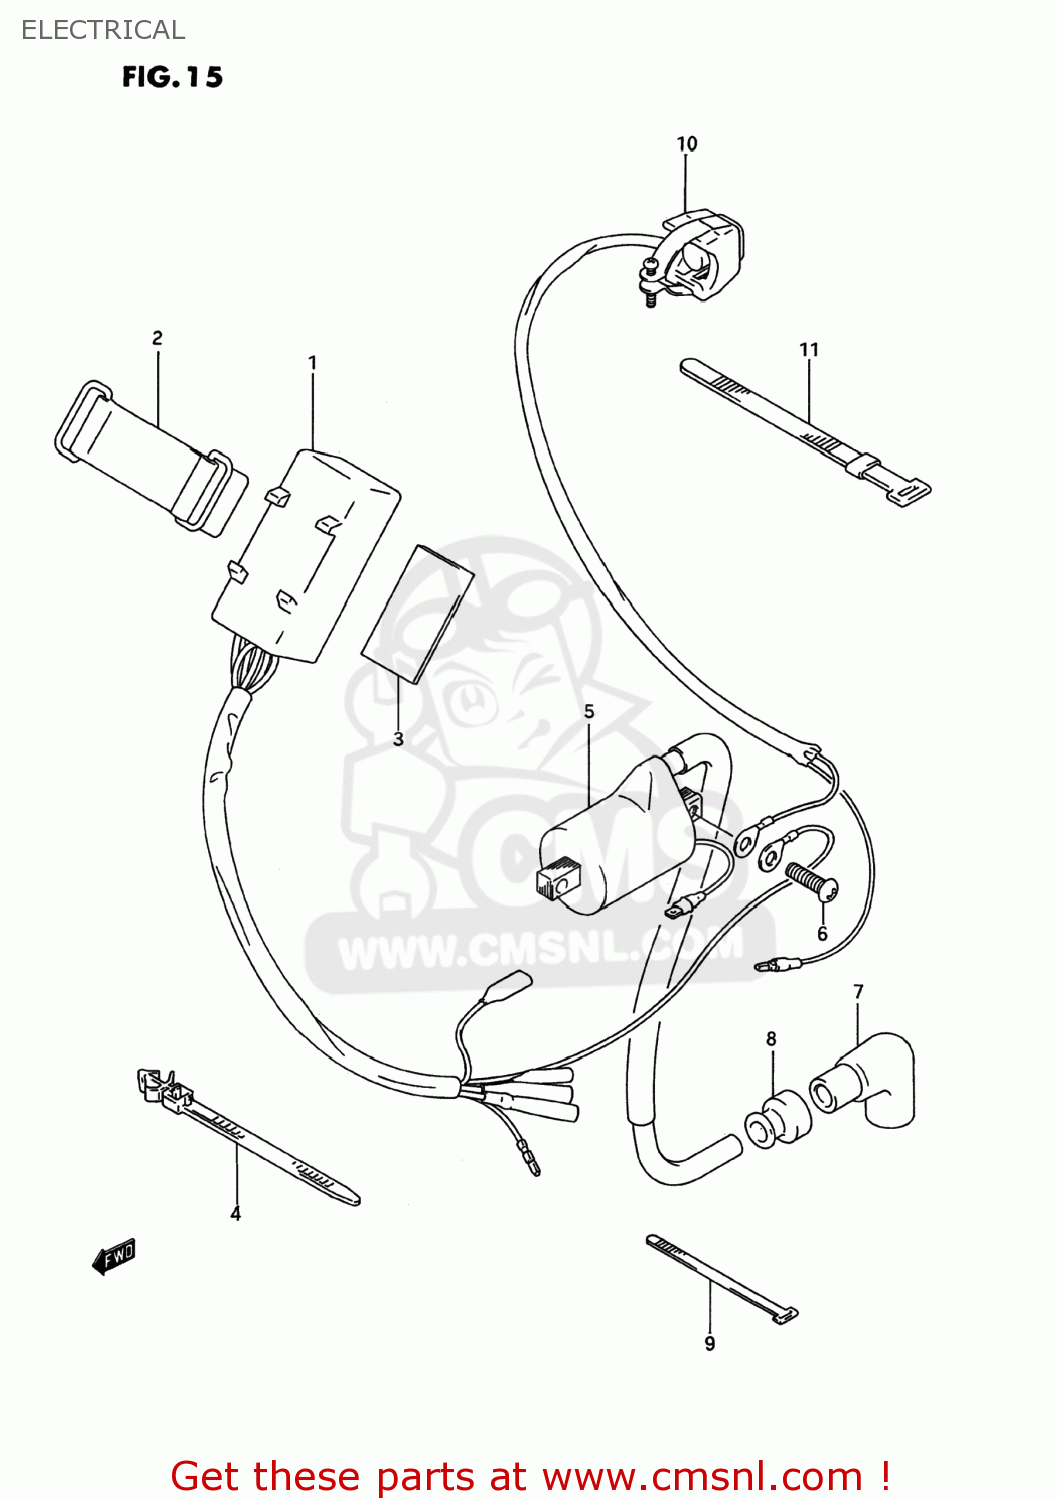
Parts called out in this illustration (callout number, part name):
1	CDI UNIT
2	BAND(L:65)
3	PROTECTOR(170X95X3.0)
4	CLAMP(L:90)
5	COIL ASSY,IGNITION
6	SCREW
7	CAP,SPARK PLUG
8	SEAL,HIGH TENSION CORD
9	CLAMP
10	SWITCH ASSEMBLY
11	CLAMP(L:120)
